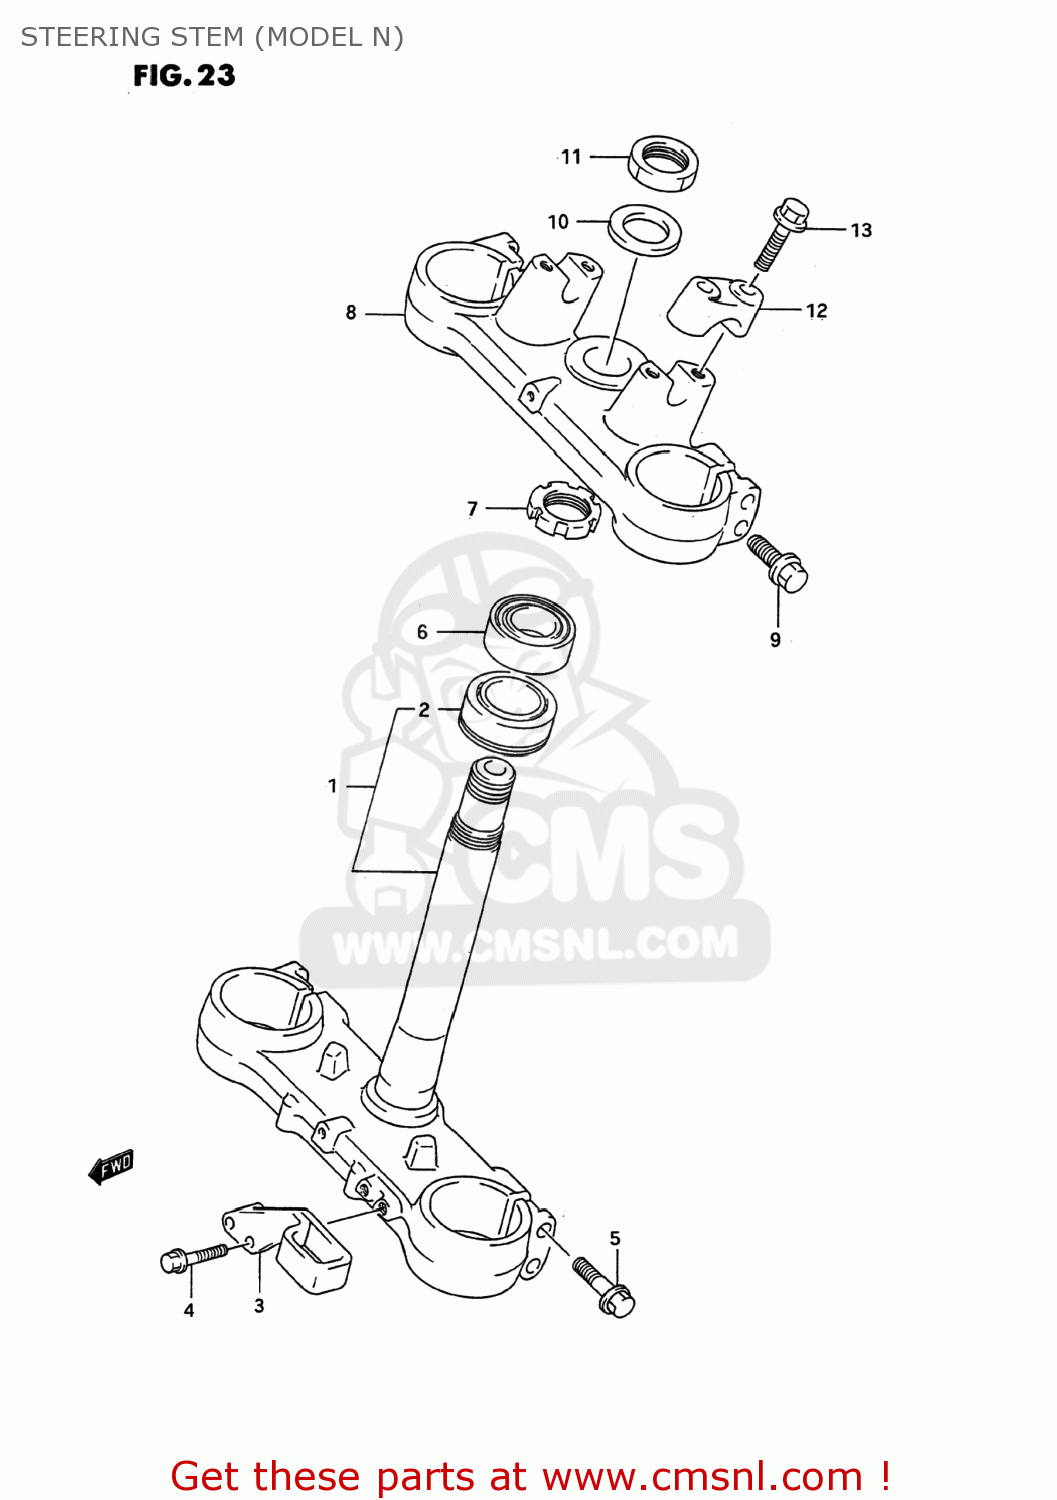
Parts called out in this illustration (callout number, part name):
1	STEM,STEERING
2	BEARING(30X52X16)
3	GUIDE,HOSE
4	BOLT,GUIDE
5	BOLT,STEM 8X45
6	BEARING(28X54X16)
7	NUT,STEERING
8	HEAD,STEERING STEM
9	BOLT,STEM 8X45
10	WASHER,STEM HEAD
11	NUT,STEM HEAD
12	HOLDER,HANDLEBAR
13	BOLT,HANDLE HOLDER(8X35)
